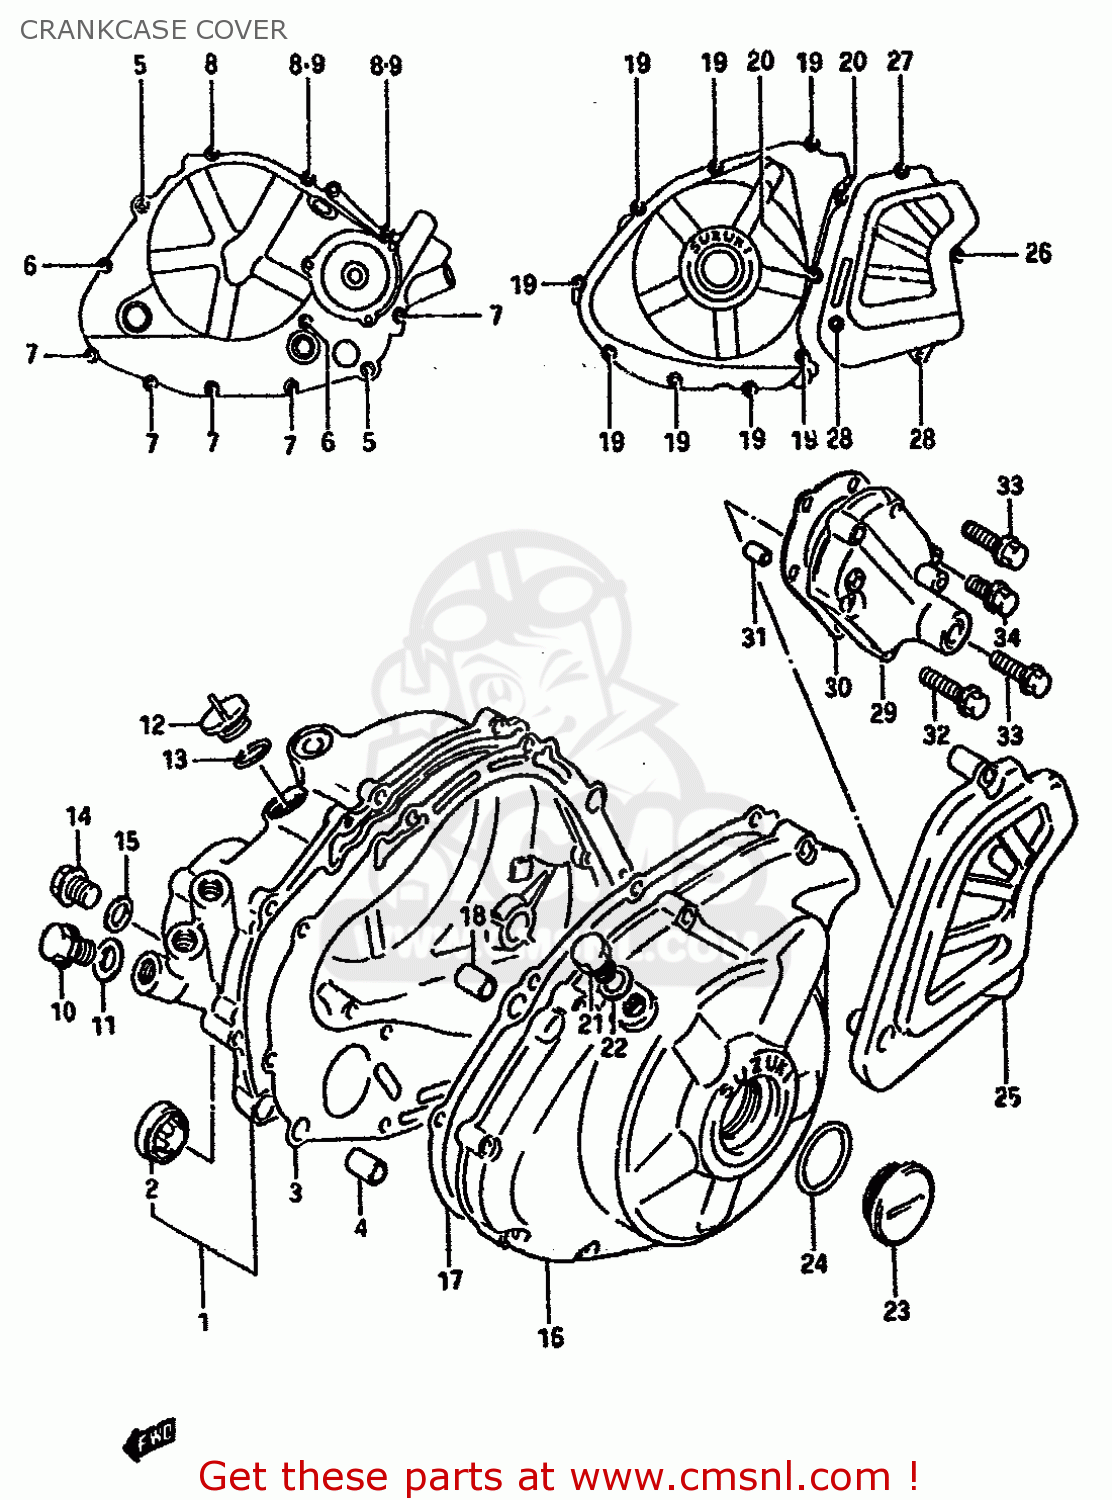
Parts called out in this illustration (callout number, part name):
1	COVER,CLUTCH
2	LENS,OIL LEVEL CHECK
3	GASKET,CLUTCH COVER
4	PIN
5	BOLT 6X50
6	BOLT 6X40
7	BOLT 6X35
8	BOLT 6X25
9	GASKET(5.8X13X1.2) (NAS)
10	PLUG(14X12)
11	GASKET(14X19.2X2) (NAS)
12	PLUG
13	O RING(D:3.1,ID:16.8)
14	PLUG(14X12)
15	GASKET(14X19.2X2) (NAS)
16	COVER,MAGNETO
17	GASKET,MAGNETO COVER (MCA)
18	PIN
19	BOLT 6X30
20	BOLT 6X25
21	PLUG(12X9)
22	GASKET(12.1X16.2X3.7) (NAS)
23	PLUG
24	O RING(D:3.1,ID:32.7)
25	COVER,ENGINE SPROCKET
26	BOLT
27	BOLT 6X35
28	BOLT 6X20
29	COVER,GEAR SHIFT
30	GASKET,GEAR SHIFT COVER (MCA)
31	PIN
32	BOLT 6X35
33	BOLT 6X30
34	BOLT 6X20
